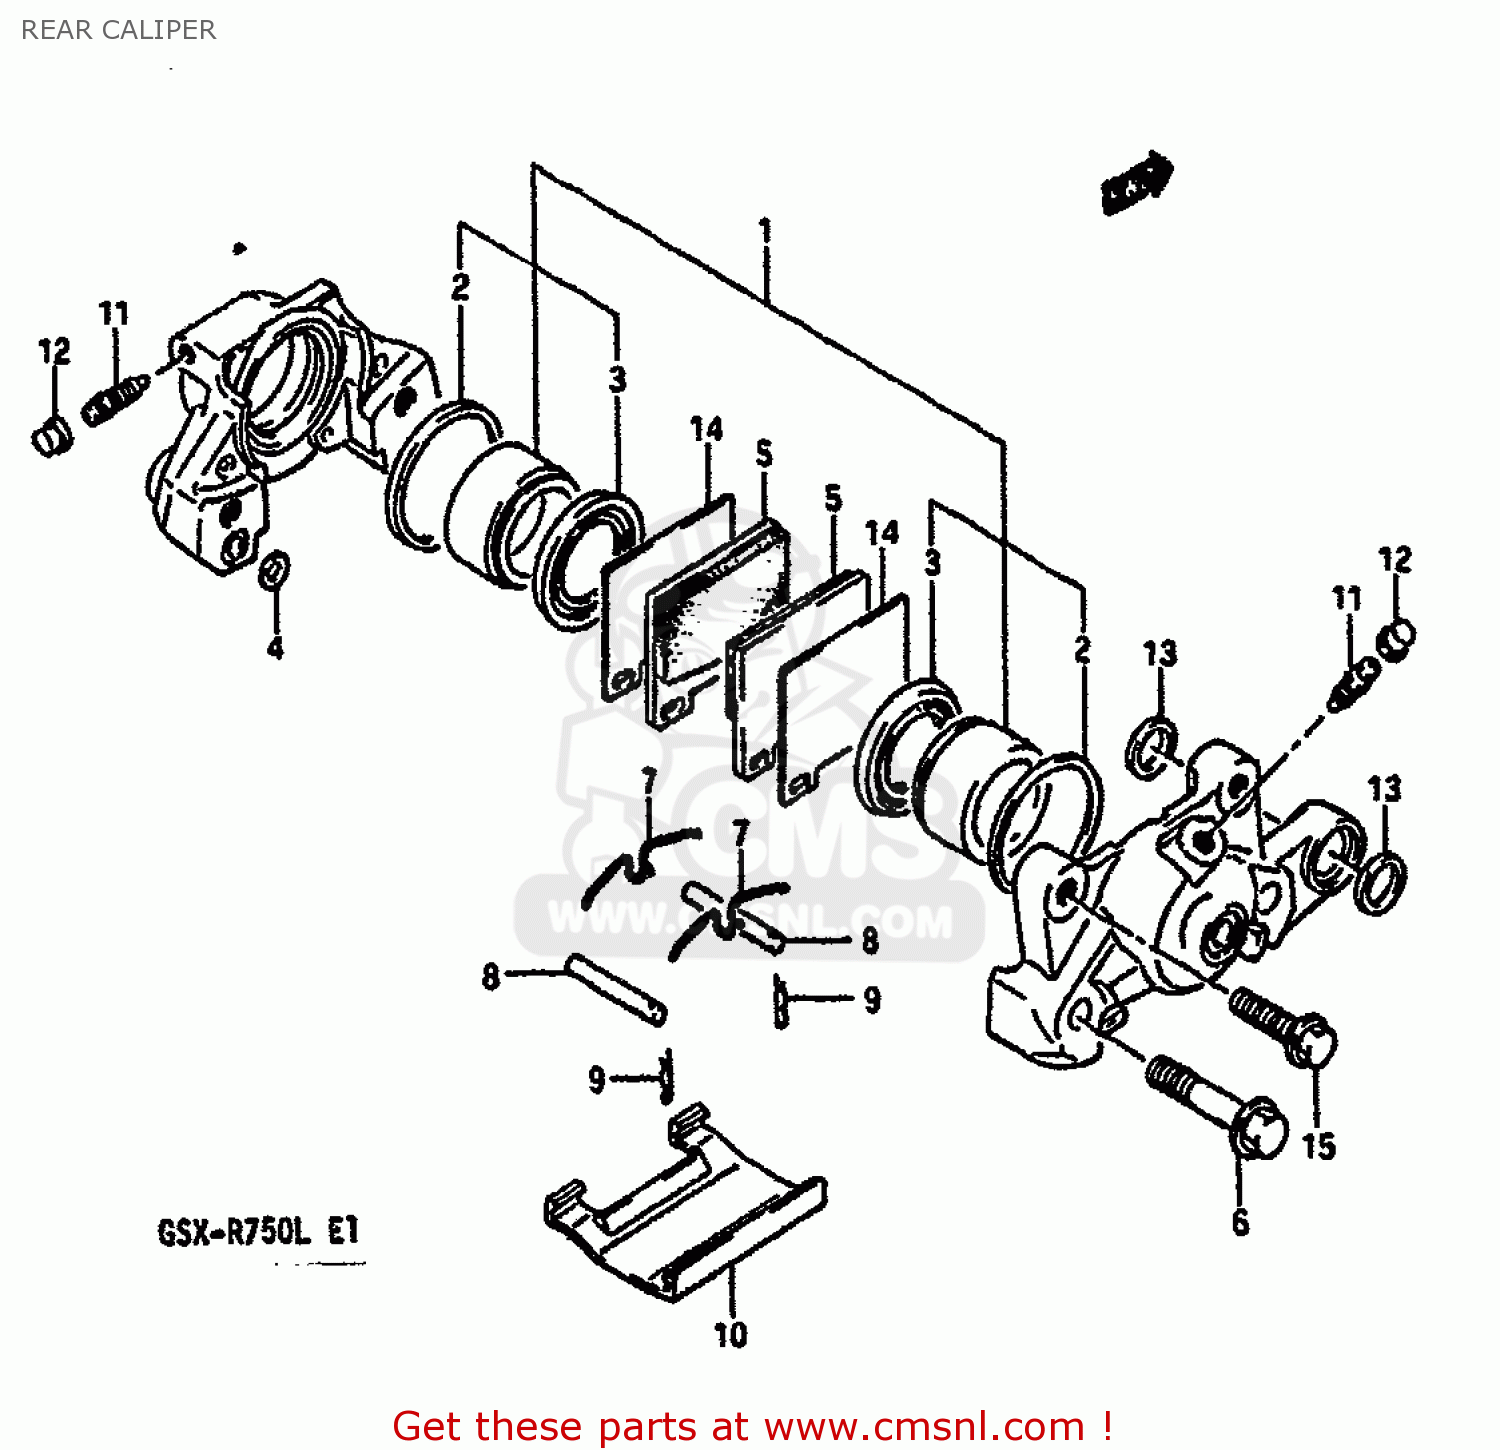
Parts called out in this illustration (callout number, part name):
1	PISTON SET
2	SEAL,PISTON
3	BOOT
4	SEAL,JOINT
5	PAD,BRAKE
6	BOLT
7	SPRING
8	PIN,PAD
9	CLIP,PAD PIN
10	COVER
11	BLEEDER
12	CAP,BREATHER
13	SEAL,RR CUSHION ROD LWR
14	SHIM,PAD
15	BOLT
